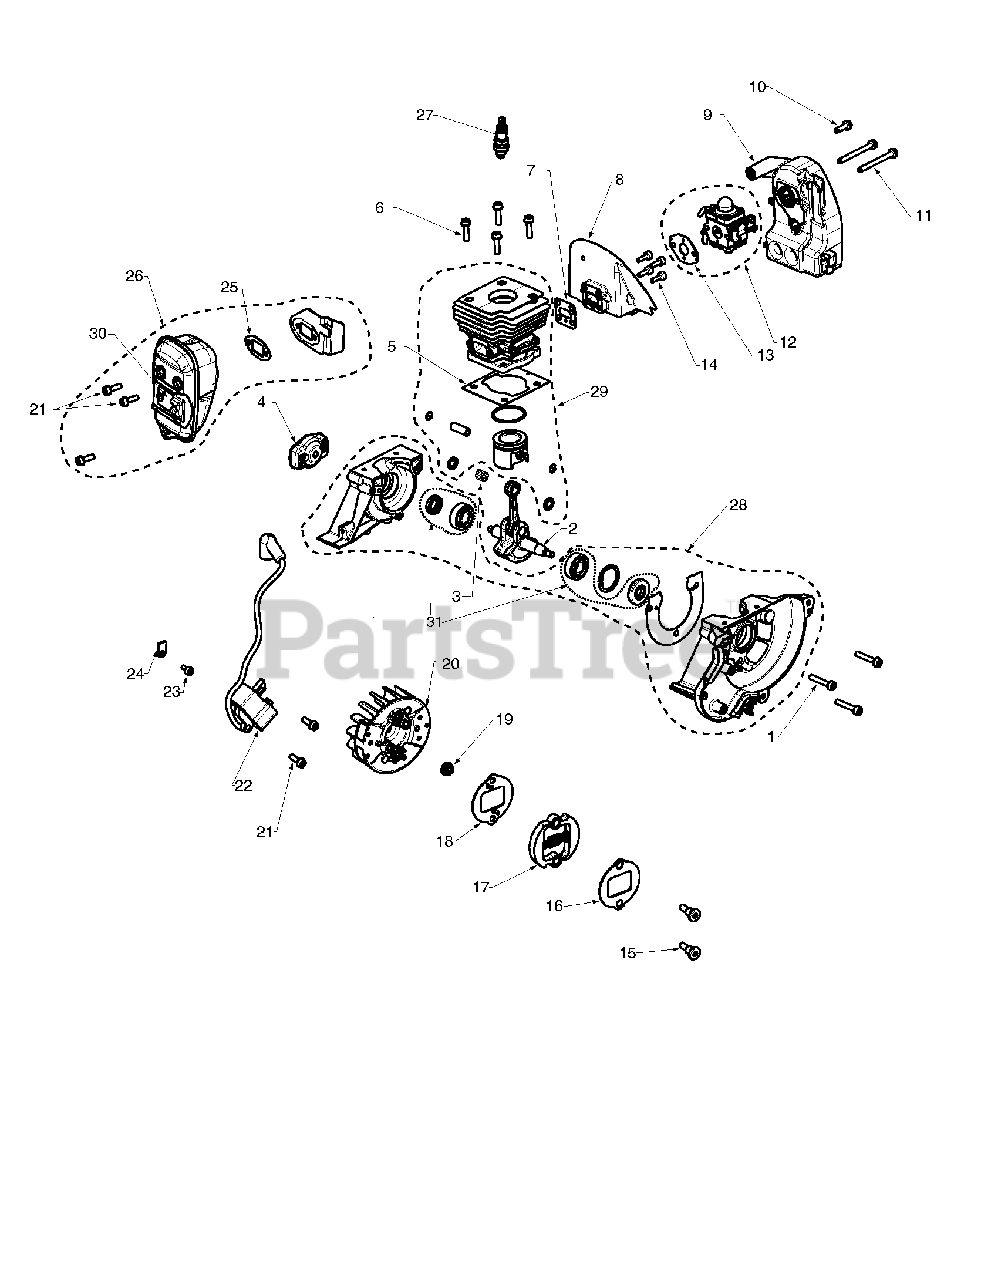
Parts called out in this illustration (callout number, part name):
2	Crankshaft Assembly
3	BEARING NEEDLE
4	Starter Pawl Bridge
5	Cylinder Base Gasket
7	GASKET INSULATION WALL
8	ASSY INSULATION WALL
9	ASSY FILTER HOLDER
12	Carburetor Kit
13	GASKET - CARBURETOR
14	Screw, ITXSCM
15	Clutch Screw
16	WASHER CLUTCH UPPER
18	WASHER CLUTCH LOWER
19	FLANGE NUT
22	Ignition Module
23	SCREW 10-24 TAPTITE
26	Muffler Kit
28	KIT CRANKCASE ASSY
29	Piston and Cylinder Kit
30	KIT SPARK ARRESTOR
31	Bearing and Seal Kit
